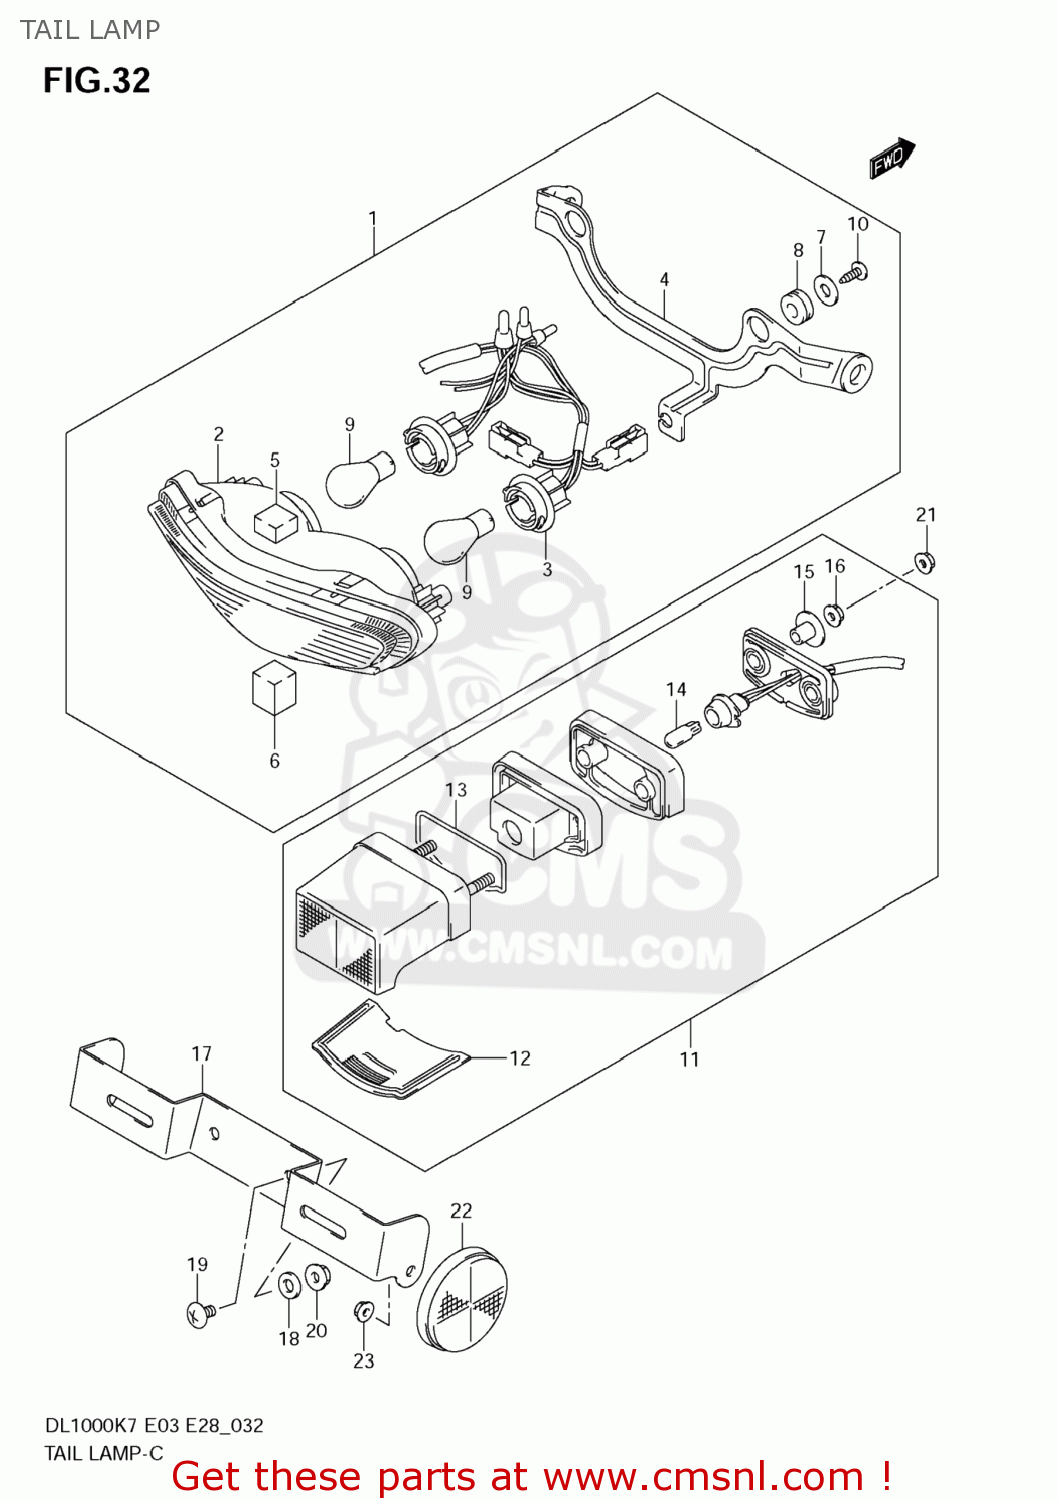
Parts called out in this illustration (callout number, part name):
1	LAMP ASSY,RR COMBINATION
2	UNIT
3	SOCKET & CORD
4	BRACKET
5	CUSHION,UPR(20X20X12)
6	CUSHION,LWR(20X20X25)
7	WASHER(5.5X20X1.2)
8	CUSHION
9	BULB(12V21/5W)
10	SCREW
11	LAMP ASSY,LICENSE
12	LENS
13	GASKET (NAS)
14	BULB(12V5W)
15	SPACER
16	NUT
17	BRACKET,LICENSE PLATE
18	WASHER(6.5X15X1.6)
19	SCREW
20	NUT
21	NUT
22	REFLECTOR ASSY,RR SIDE
23	NUT
